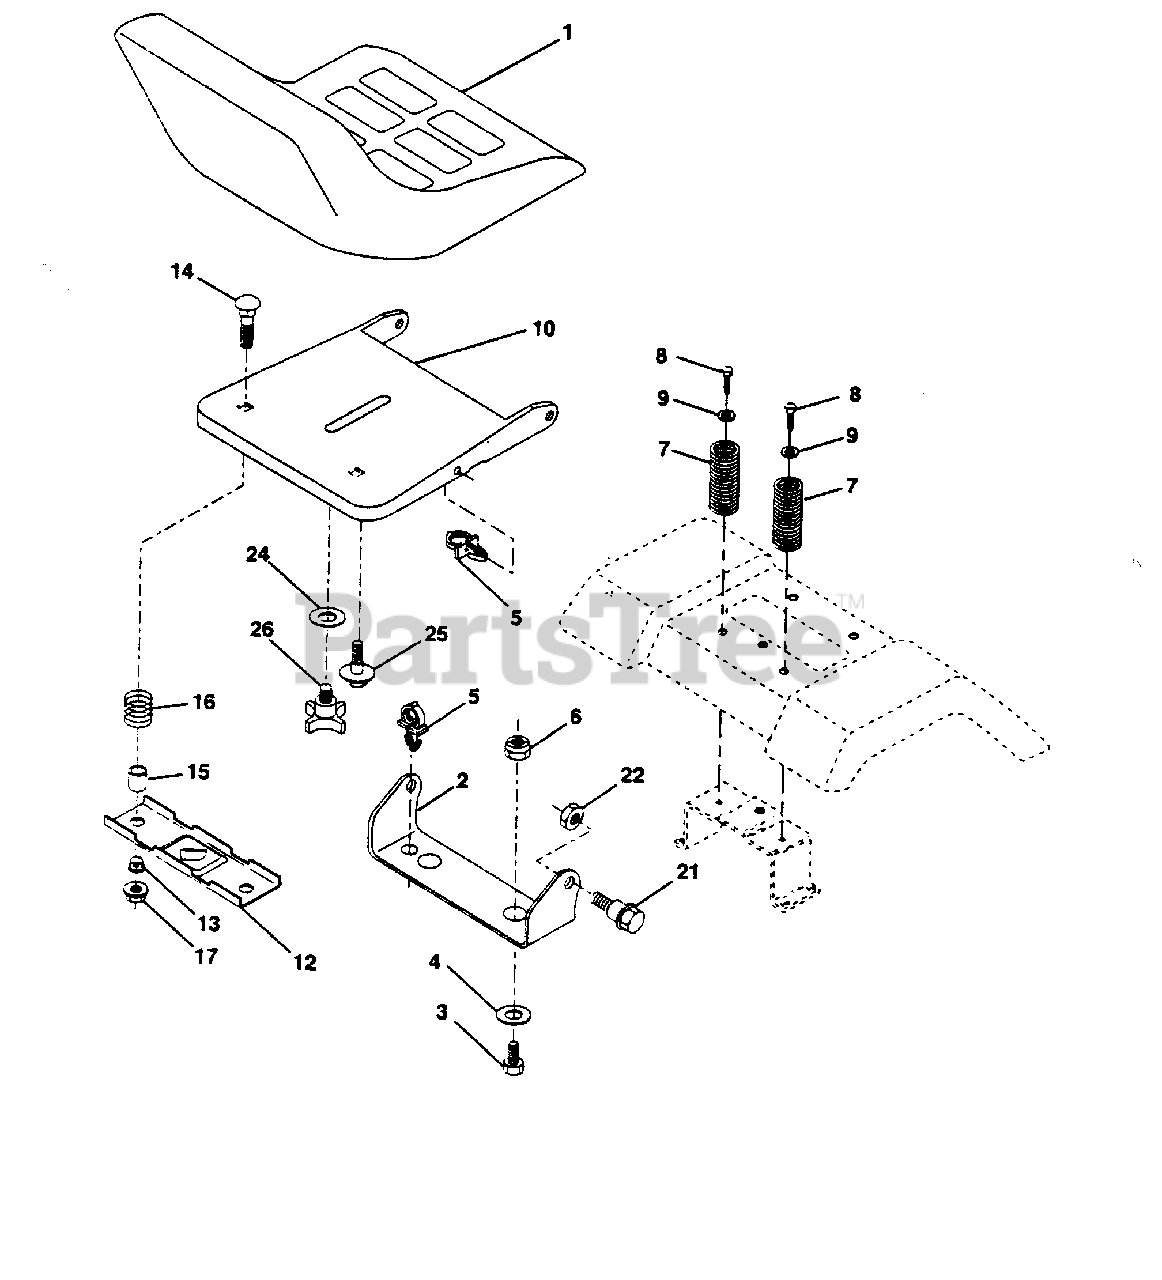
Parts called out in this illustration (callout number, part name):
1	Seat V450 Blk/blk Std (AYP part number)
2	Bracket Pivot Seat 8 720 (AYP part number)
3	Bolt Fin Hex 3/8-16unc X 1 (AYP part number)
4	Washer 13/32 X 1 X 10 Ga (AYP part number)
5	Clip Push-In (AYP part number)
6	Nut Crownlock 3/8-16 Unc
7	Spring Seat Cprsn 2 250 Blk Zi (AYP part number)
8	Screw Thdrol 3/8-16 X 1 Ty-tt (AYP part number)
9	Washer 13/32 X 1 X 14 Ga. (AYP part number)
10	Pan Seat (AYP part number)
12	Bracket Mounting Switch (AYP part number)
13	Bushing Snap Blk Nyl 50 ld (AYP part number)
14	Bolt Rdhd Sht Nk 1/4-20x1-3/8
15	Spacer Split 28x 96 Yel Zinc (AYP part number)
16	Spring Cprsn 1 27 Blk Pnt (AYP part number)
17	Nut Lock 1/4 Lge Flg Gr 5 Zinc (AYP part number)
21	Bolt Shoulder 5/16-18 Unc Blkz (AYP part number)
22	Nut Hex Lock W/Ins 5/16-18 (AYP part number)
24	Washer 17/32 X 1-3/16 X 12 Ga. (AYP part number)
25	Bolt Shoulder 5/16-18 X 62 (AYP part number)
26	Knob Seat 1/2 - 13 Unc Blk (AYP part number)
